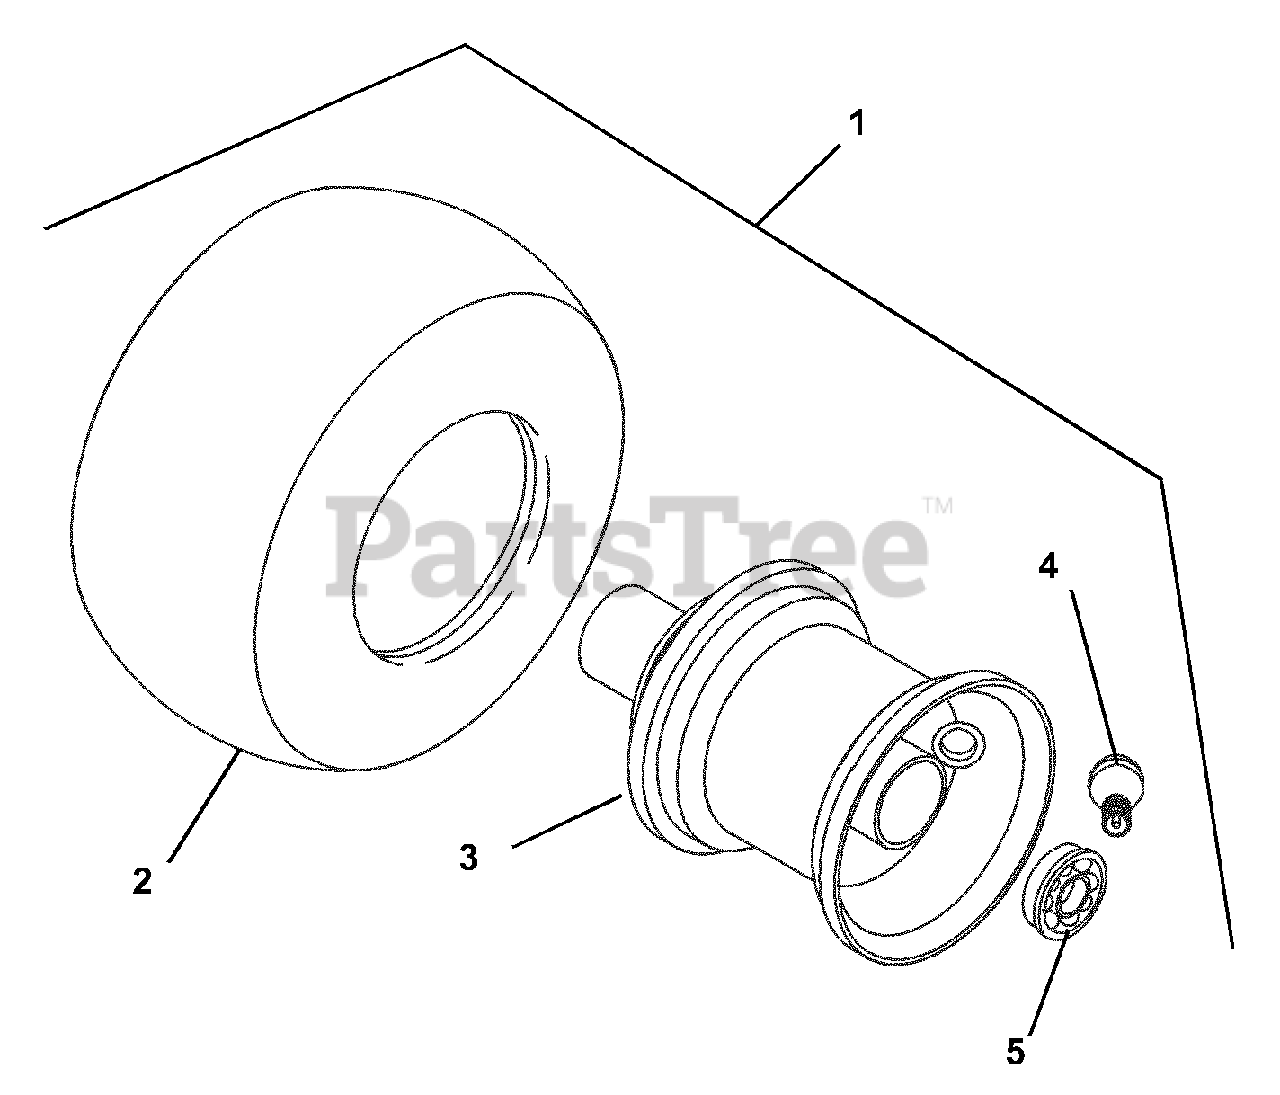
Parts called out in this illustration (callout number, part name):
1	ASSY,WHL & TIRE 16X650
2	TIRE16X650-8 4PLY RPLD 71220
3	ASSY, WHEEL
4	VALVE STEM ASS'Y
5	BEARING, 1" SEALED
